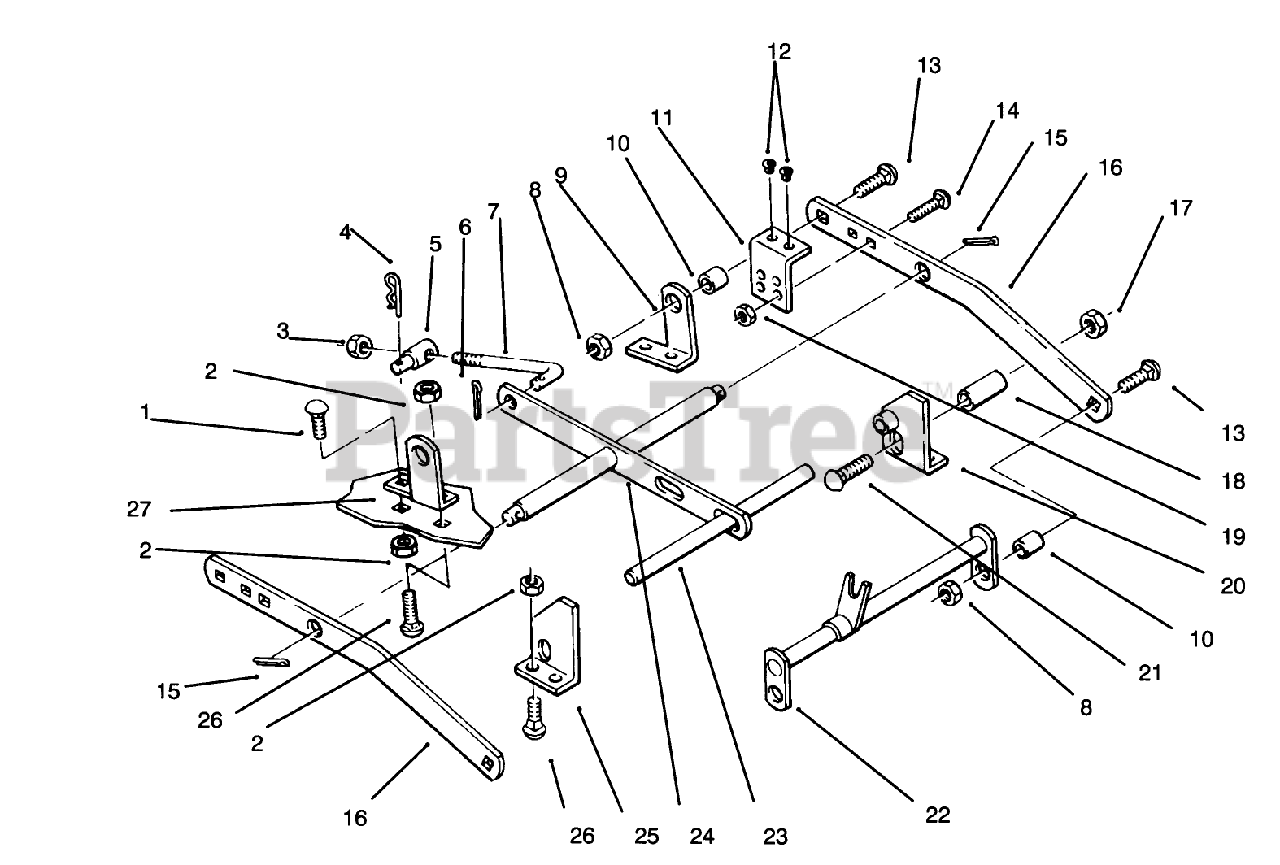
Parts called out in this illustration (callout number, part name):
1	Bolt
2	NUT-HEX
3	NUT-LOCK, NI
4	Hairpin
5	TRUNNION-LIFT
6	PIN-COTTER
7	ROD-LEVEL ADJUST
8	LOCKNUT-FLANGE
9	LH Rear Bracket
10	SPACER
11	Bumper-Metal
12	BUMPER-RUBBER
13	BOLT-CARR
14	BOLT-CARR
15	Cotter Pin
16	Bar Draft
17	Nut
19	Nut
20	Front Bracket LH
21	BOLT-CARR
22	Hitch
23	Front Shaft
24	Leveler
25	Front Bracket RH
26	SCREW-CARR
27	Rear Bracket RH
